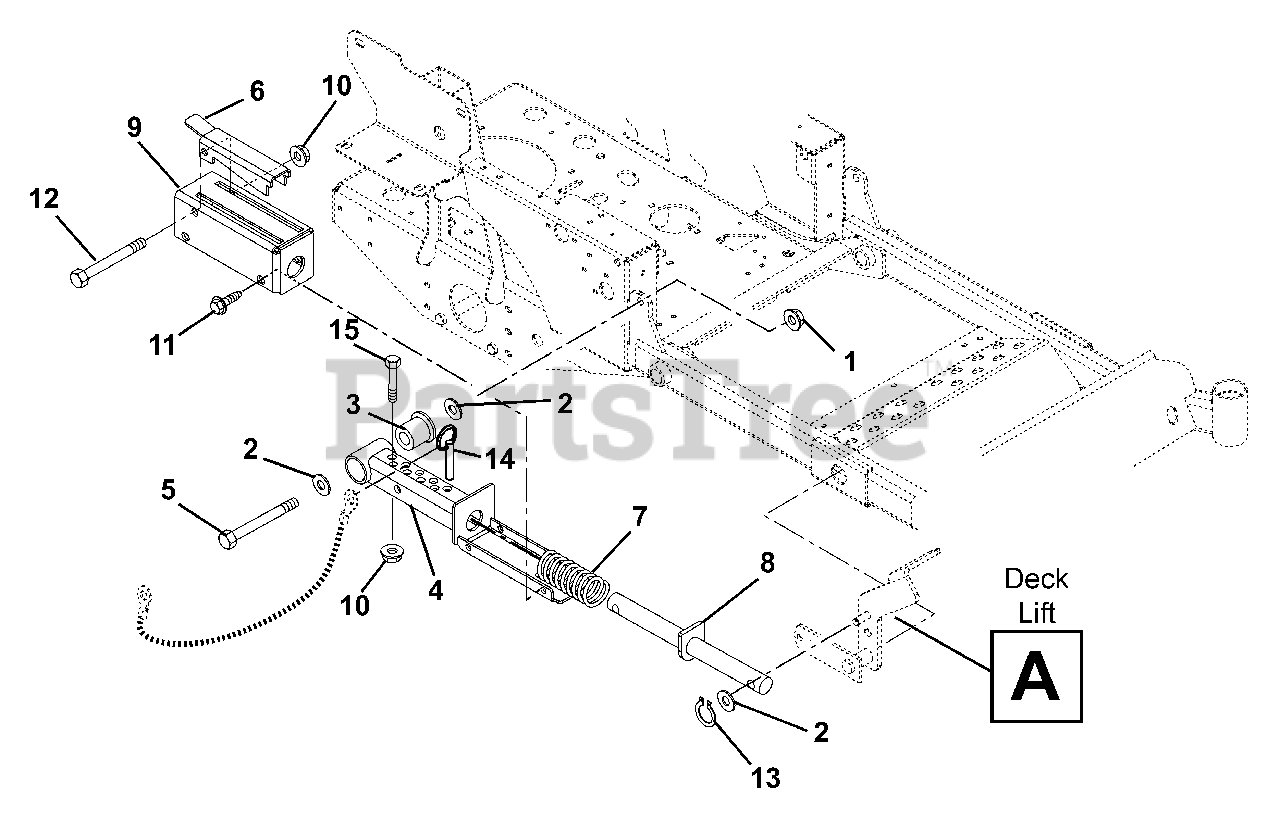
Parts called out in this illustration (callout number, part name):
1	Nut, Locking Top Flange .50-13
2	Washer, Flat Steel .531 x 1.25 x .10
3	Bearing, Pedestal Powdered Metal
4	Weldment, Mechanical Lift
5	Bolt, Hex .50-13 x 3.75 Grade 5
6	Lock-Up, Mechanical Lift
7	Spring, Compression 1.13 x 1.48 x 5.10
8	Weldment, Mechanical Lift Shaft
9	Weldment, Mechanical Lift Cover
10	Nut, Nyloc Flange 3/8-16
11	Screw, Tapping .38-16 x .50 Hex Washer Head
12	Bolt, Hex .38-16 x 3.25 Grade 5
13	Ring, Retaining External .50 x .05
14	Pin, Spring Ball .375 O.D. x 1.50
15	Bolt, Hex .38-16 x 2.00 Grade 5
